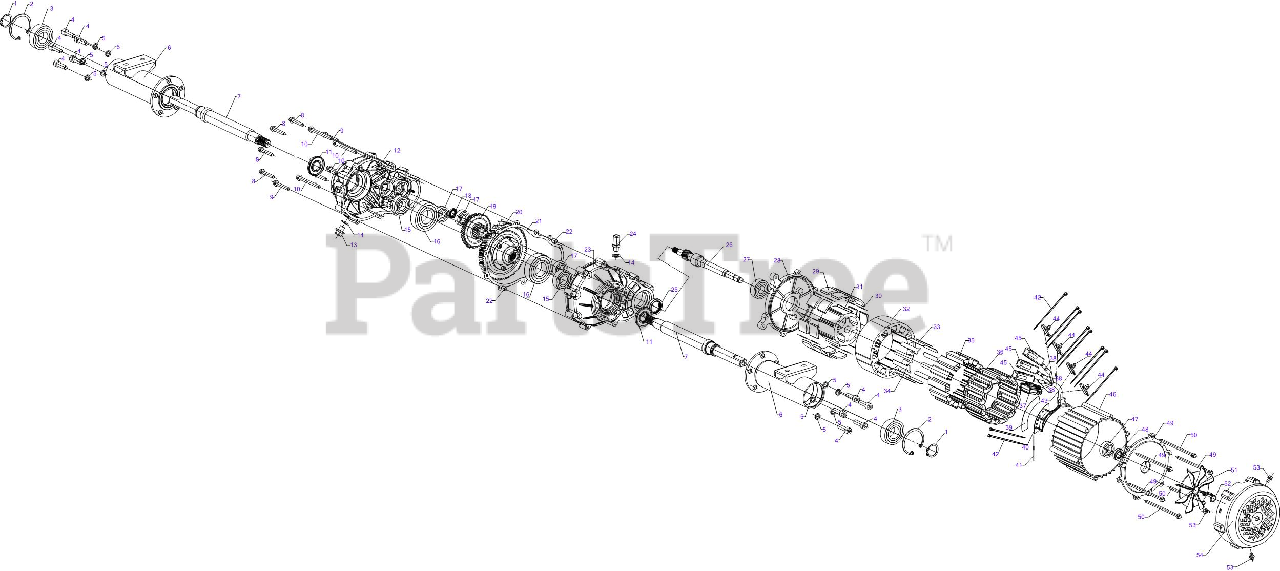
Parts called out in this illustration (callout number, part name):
1	EXTERNAL RETAINING RING
2	INNER RETAINING RING
3	SEALED BALL BEARING (25 x 25 x 15)
4	SCREW (M8-1.25 x 25 GRX STD)
5	SPLIT LOCK WASHER M8
6	AXLE SUPPORT (RH)
6	AXLE SUPPORT (LH)
7	AXLE (RH) (12.4 x .75)
7	AXLE (LH) (12.4 x .75)
8	SCREW (M6-1x35 GRX SPEC)
9	SCREW (M6-1x40 GRX SPEC)
10	SCREW (M6-1x65 GRX SPEC)
11	OIL SEAL (20 x 42 x 5)
12	CRANKCASE COVER
13	SCREW (M10-1.25x10 GRX SPEC)
14	FLAT WASHER (M10 x 16 x 1.5)
15	SEALED BALL BEARING (20 x 42 x 12)
16	SEALED BALL BEARING (30 x 62 x 16)
17	SEALED BALL BEARING (12 x 32 x 10)
18	OIL SEAL (12 x 24 x 4)
19	SPUR GEAR (72-20)
20	DIFFERENTIAL SPUR ASSEMBLY (77T)
21	TRANSMISSION HOUSING GASKET
22	SLEEVE (8 x 10 x 6.3)
23	CRANKCASE
24	TRANSMISSION HOUSING BREATHER
25	OIL SEAL (17 x 35 x 7)
26	MOTOR SHAFT
27	BEARING
28	CONNECTING COVER
29	SHOE
30	PIN
31	ROTOR CORE
32	STATOR CORE
33	LAMINATION
34	LAMINATION
35	PAPER
36	WIRE
37	CONNECTOR
38	PHASE WIRE TERMINAL
39	INSULATION BOARD
40	ASSEMBLY
41	THERMISTOR
42	RIBBON
43	LEADING WIRE
44	ARROW CLIP
45	PHASE WIRE CONNECTOR
46	STATOR COVER
47	BEARING
48	REAR COVER OIL SEAL
49	REAR COVER
50	BOLT
51	FAN
52	RETAINER
53	SCREW
54	FAN SHROUD
